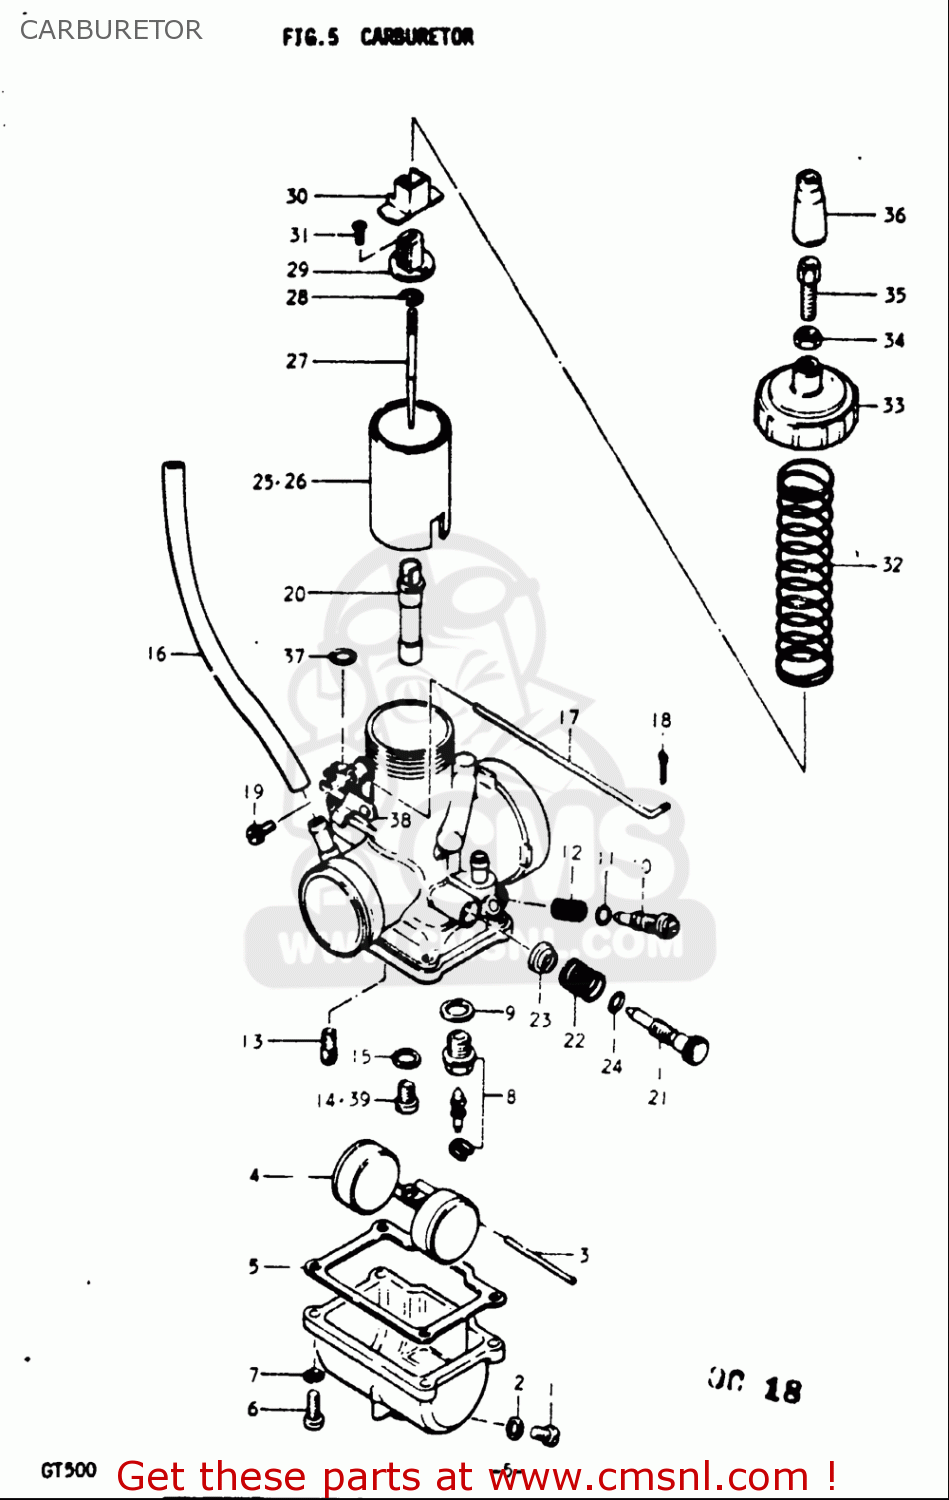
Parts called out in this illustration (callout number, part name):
1	PLUG
2	GASKET,DRAIN,PLUG (NAS)
3	PIN,FLOAT
4	FLOAT
5	GASKET,FLOAT CAHMBER (NAS)
6	SCREW 4X16
7	WASHER,LOCK
8	VALVE ASSY,NEEDLE
9	GASKET,MAIN JET HOLDER (NAS)
10	SCREW,PILOT AIR ADJUSTING
11	O RING
12	SPRING
13	JET,PILOT(30)
14	JET,MAIN(97.5)
15	WASHER
16	HOSE(4.5X8.5X600)
17	ROD,STARTER LEVER
18	PIN 12X10
19	BOLT, STARTER ROD
22	SPRING,THROTTLE STOP
23	COVER
24	O RING
